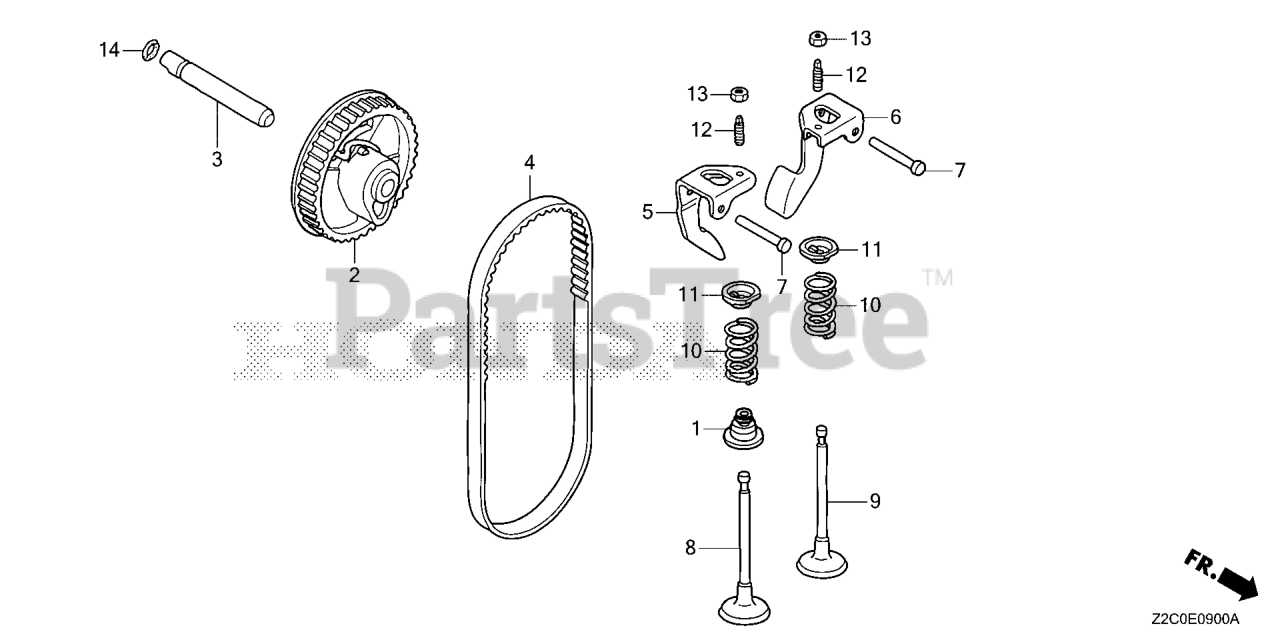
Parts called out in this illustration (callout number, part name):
1	SEAL, VALVE STEM
2	PULLEY, CAMSHAFT
3	SHAFT, CAM PULLEY
4	BELT, TIMING (84HU6 G-200)
5	ARM, IN. VALVE ROCKER
6	ARM, EX. VALVE ROCKER
7	SHAFT, ROCKER ARM
8	VALVE, IN. (TECHNOSTAR)
9	VALVE, EX. (L8E)
9	VALVE, EX. (C8E)
10	SPRING, VALVE
11	RETAINER, VALVE SPRING
12	SCREW, TAPPET ADJ.
13	NUT, TAPPET ADJ.
14	O-RING (6.8X1.9) (ARAI)
